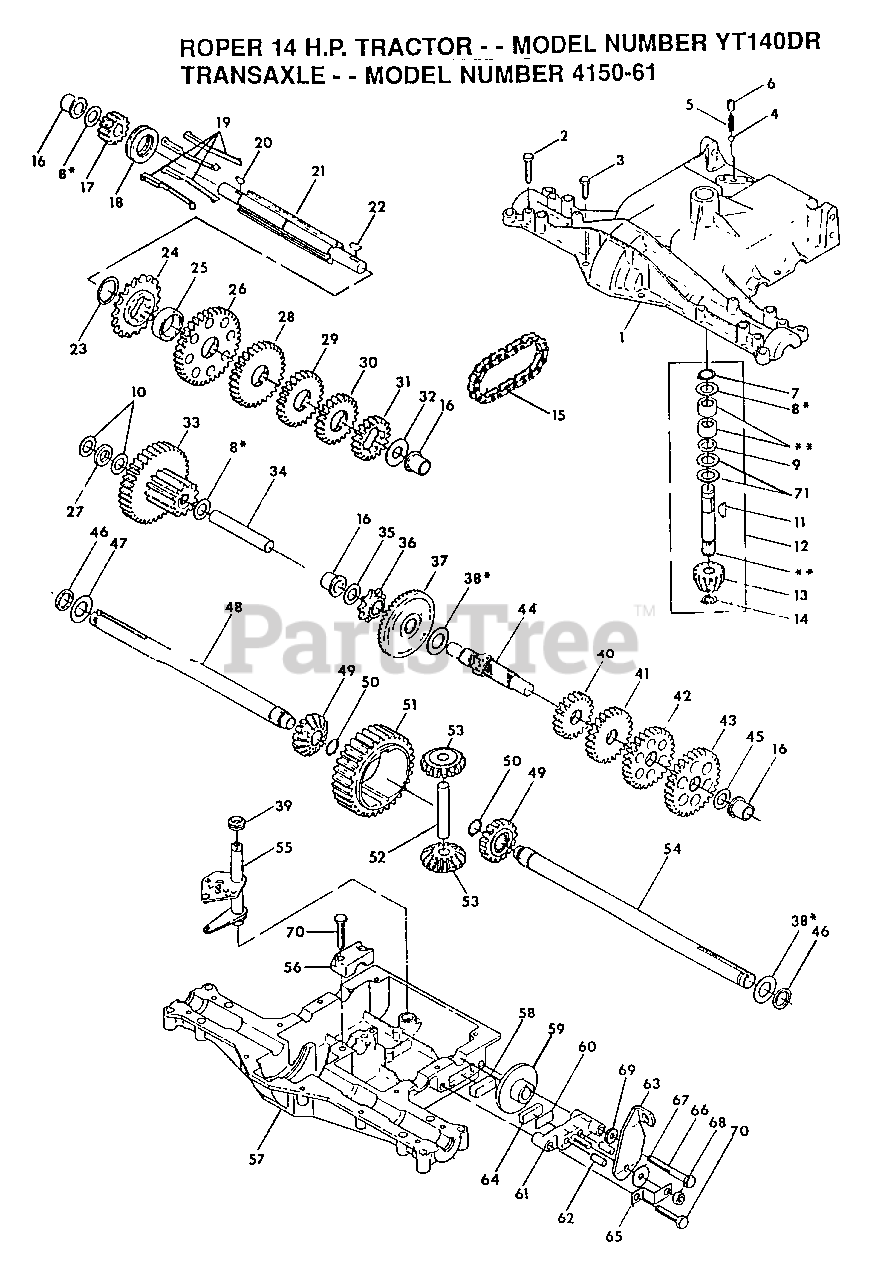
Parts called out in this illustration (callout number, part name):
1	HOUSING, UPPER
2	SCREW 1/4-20 X 1.31
3	SCREW 1/4-20 X .875
4	BALL DETENT
5	SPRING, DETENT
6	SCREW, SET
7	RING RETAINING
8	WASHER PLAIN
8	WASHER, PLAIN .632 X 1.00 X .026
8	WASHER, PLAIN .632 X 1.00 X .060
10	WASHER PLAIN
11	KEY WOODRUFF #9
12	ASSY KIT INPUT SHAFT
13	PINION BEVEL 14 TEETH
14	RING, RETAINING
15	CHAIN, 24 PITCHES
16	BEARING, FLANGE
17	GEAR, SPUR 14T
18	COLLAR CLUTCH
19	KEY, CLUTCH
20	KEY WOODRUFF #3
21	SHAFT, INTERMEDIATE
22	KEY, WOODRUFF, #61
23	RING, RETAINING
24	SPROCKET, 18T
26	GEAR, SPUR 40T
27	SPACER .630 X 1.00 X .169
28	GEAR, SPUR, 35 TEETH
29	GEAR, SPUR, 25 TEETH
30	GEAR, SPUR, 22 TEETH
32	WASHER, PLAIN .640 X 1.37 X .061
33	ASSY, GEAR, COMB., 12T & 35T
34	SHAFT, IDLER
35	WASHER PLAIN
36	SPROCKET, 9 TEETH
37	GEAR, BEVEL, 42 TEETH
38	WASHER PLAIN
38	WASHER, PLAIN .758 X 1.25 X .031
39	WASHER PLAIN
40	GEAR SPUR, 15 TEETH
41	GEAR, SPUR, 25 TEETH
42	GEAR, SPUR, 28 TEETH
43	GEAR, SPUR, 31 TEETH
44	SHAFT, DRIVE
45	WASHER, PLAIN .632 X 1.00 X .060
47	WASHER, PLAIN .758 X 1.25 X .031
49	GEAR MITER 15 TEETH
50	RING, RETAINING
51	No Desciption for Part
52	SHAFT, CROSS
53	GEAR, MITER, 15 TEETH
55	No Desciption for Part
56	CAP, SUPPORT
57	HOUSING, LOWER
58	PUCK, FRICTION
59	DISC, BRAKE
61	JAW, BRAKE
62	PIN, DOWEL
63	LEVER, ACTUATING
64	PUCK, FRICTION
65	BRACKET, ANTI-ROTATION
66	SCREW TAPPING
67	WASHER, PLAIN .321 X 1.00 X .055
68	LOCKNUT 5/16-24
69	WASHER PLAIN
70	SCREW TAPPING
71	WASHER, PLAIN .632 X 1.38 X .046
